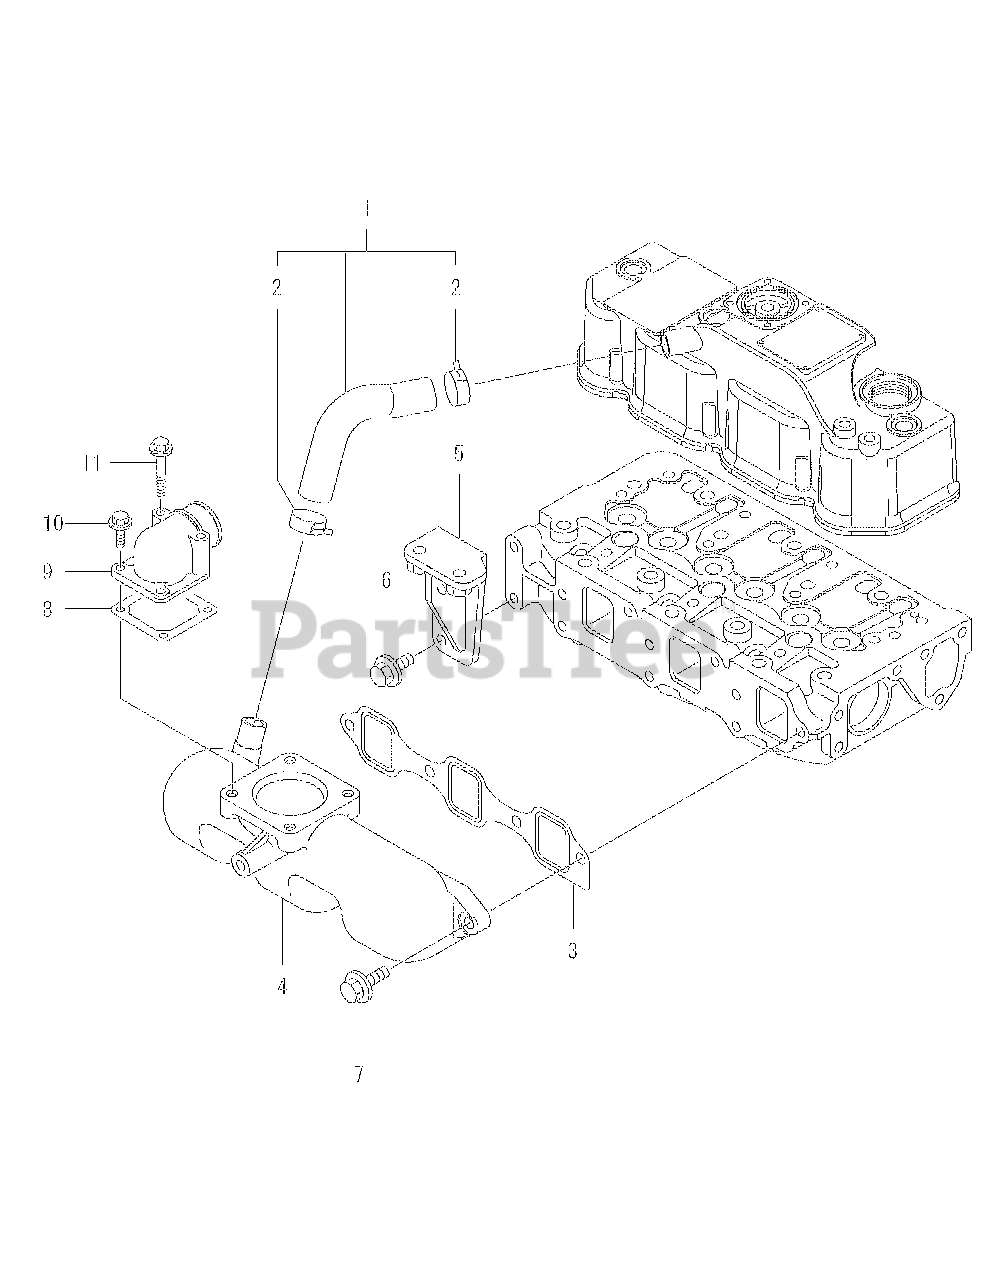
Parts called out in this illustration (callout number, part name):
3	Manifold Gasket
4	Intake Manifold
5	Filter Bracket
8	Air Heater Gasket
